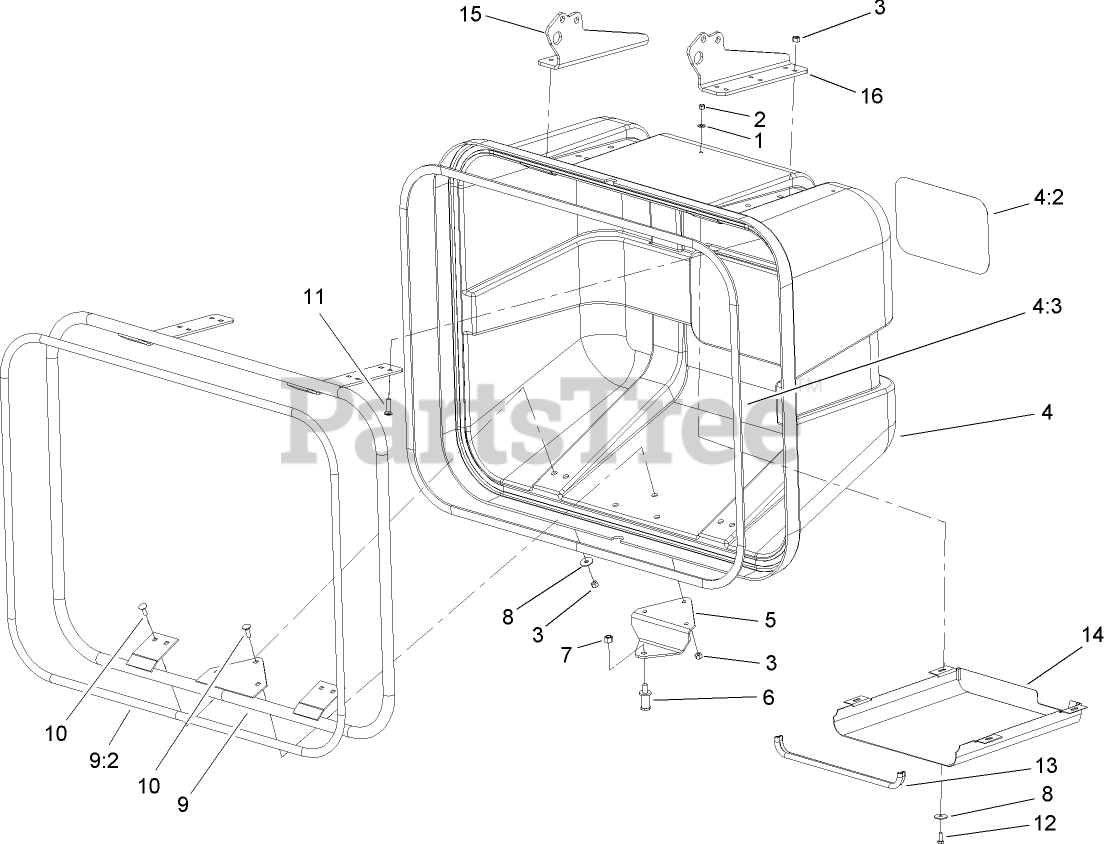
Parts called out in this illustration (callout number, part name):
1	WASHER-FLAT
2	NUT-LOCK, NI
3	NUT-LOCK, NI
4	DOOR ASM
4:2	DECAL
4:3	SEAL-HOPPER
5	BRACKET-LATCH, DOOR
6	BOLT-STRIKER
7	NUT-LOCK, NI
8	WASHER-FLAT
9	DOOR FRAME ASM
9:2	SEAL-HOPPER, ROUND
10	BOLT-CARR
11	SCREW-CARR
12	SCREW-HH
13	SEAL-TRIM
14	REAR SCREEN ASM
15	RH HINGE ASM
16	LH HINGE ASM
